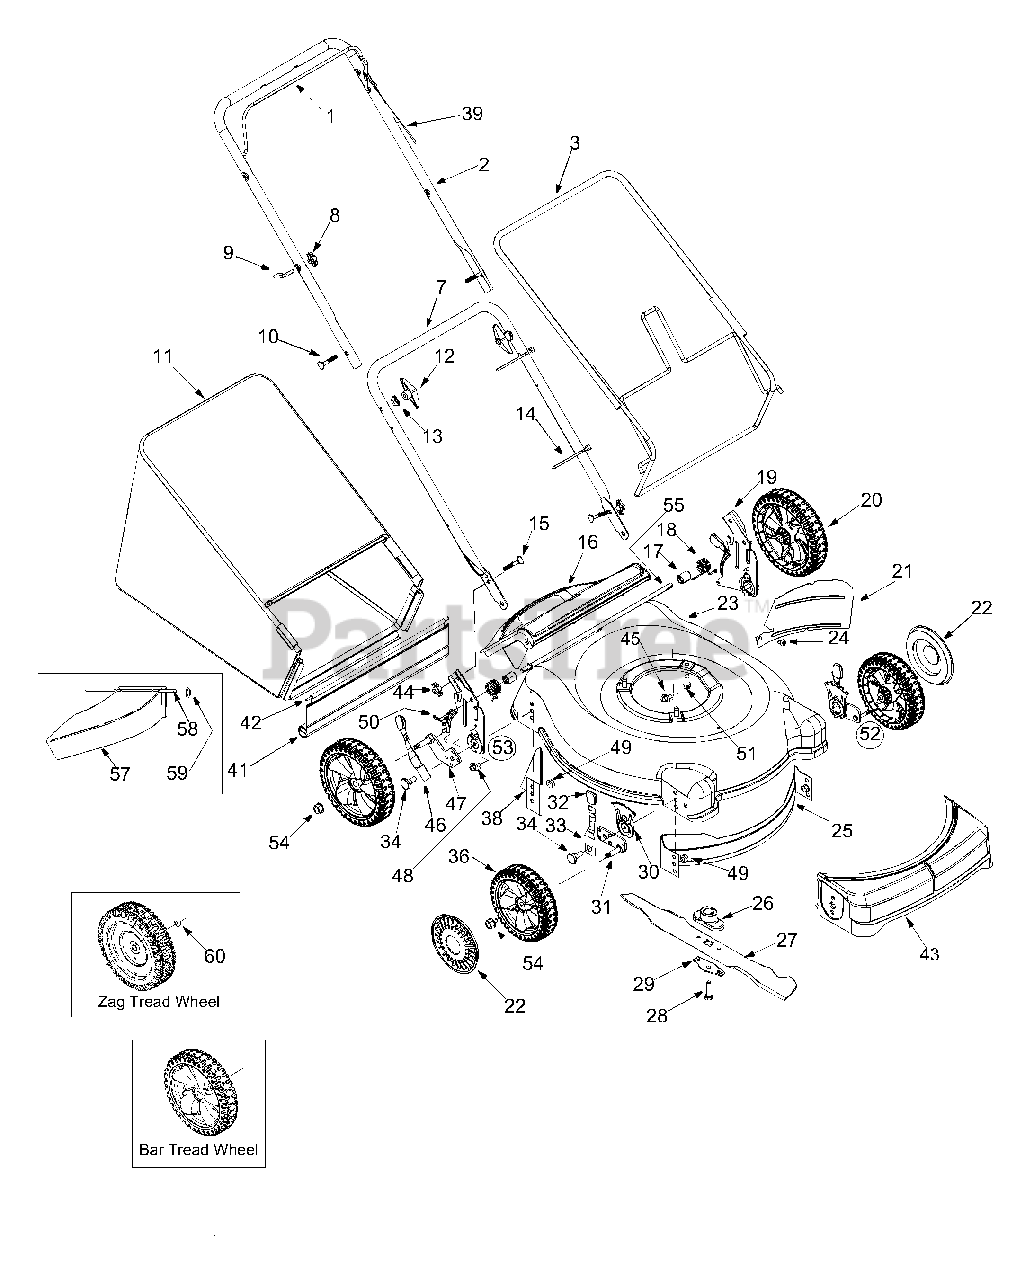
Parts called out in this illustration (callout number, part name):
8	Wing Nut
9	Rope Guide
10	Carriage Bolt 5/16-18 x 2
11	Grass Bag Assembly
12	Hand Knob
13	Saddle Washer
14	Cable Tie
15	Carriage Bolt 1/4-20
16	Rear Discharge Door
17	Spacer
18	Torsion Spring LH
18	Torsion Spring RH
19	Handle Bracket RH
19	Handle Bracket LH
20	Rear Wheel Refer to "Wheel Chart"
22	Hubcap If equipped
24	AB Screw 1/4-14 x .625"
27	Mulching Blade
28	Hex Bolt 3/8-24 x 1.5
29	Blade Bell Support
30	Front Adjustment Plate
31	Pivot Arm Assembly RH (8" wheel)
31	Pivot Arm Assembly LH (7" wheel)
31	Pivot Arm Assembly LH (8" wheel)
31	Pivot Arm Assembly RH (7" wheel)
32	Knob: Adjustment Lever
33	Spring Lever Assembly
34	Shoulder Screw
36	Front Wheel Refer to "Wheel Chart"
39	Control Cable 37.25"
39	Control Cable 40"
39	Control Cable 40.5"
39	Control Cable 53"
41	Trailshield
42	Trailshield Wire
43	Deck: Front Cover
44	Wing Nut 1/4-20
45	Hex L-Washer Hd. Screw 3/8-16 x 1.0
46	Lever Assembly: Rear Height Adj. RH
46	Lever Assembly: Rear Height Adj. LH
47	Pivot Bar: 9 Position RH
47	Pivot Bar: 9 Position LH
48	AB Screw
49	Flange Lock Nut 3/8-16
50	Hairpin Clip
51	TT Sems Screw 3/8-16 x 1.0
52	Ht. Adj. Assy. Front RH (8" Wheel)
52	Ht. Adj. Assy. Front RH (7" Wheel)
52	Ht. Adj. Assy. Front LH (8" Wheel)
52	Ht. Adj. Assy. Front LH (7" Wheel)
53	Handle Bracket Assy. Rear LH
53	Handle Bracket Assy. Rear RH
54	Flange Nut 3/8-16 Thd.
55	Pivot Rod: Rear Door
56	Wave Washer
57	Chute Deflector
58	Rod
59	Push Speed Nut
60	Spacer
